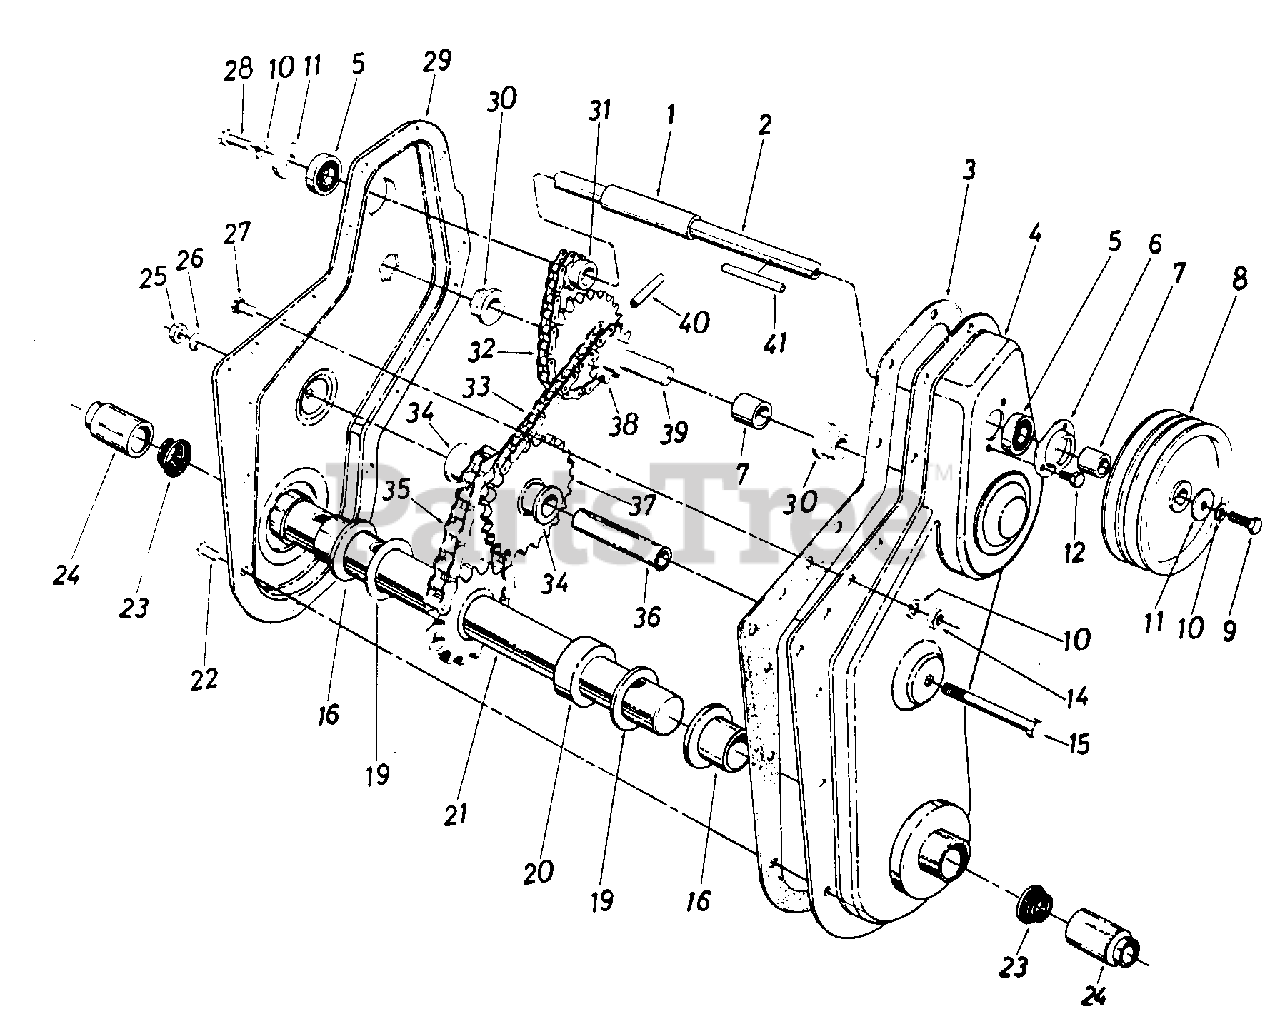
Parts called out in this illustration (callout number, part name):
2	SHAFT-JACK
3	GASKET
4	CHAIN CASE HALF-LH
5	BEARING-BALL
6	HOUSING-BRG
7	SPACER-.635 ID X .88 OD X 1.03
9	SCREW-HEX 5/16-18 X 10 SPEC
10	WASHER-LOCK-5/16
11	WASHER-FL-.312 X 1.125 X .125
12	SCREW-HEX WASH SF TAPP
14	NUT-HEX 5/16-18
15	SCREW-HEX 3/8-16 X 3.25
16	BEARING-KING PIN
19	WASHER-FL-1.03 ID X 1.62 X .03 HD
21	SHAFT-TINE
22	SCREW-HEX WASH SF TAPP
24	CAP-DUST
25	NUT-HEX 3/8-16
26	WASHER-LOCK-3/8
27	SCREW-HEX SEMS 5/16-18 X 1.00
28	SCREW-HEX 5/16-18 X .62
29	CHAIN CASE HALF-RH
30	BEARING-HEX FLANGE
31	SPROCKET ASSY-10T
32	#41 CHAIN 1/2 PITCH X 34 LINKS E
33	#420 CHAIN 1/2 PITCH X 48 LINKS
34	BEARING-FLANGE .626 ID
35	#50 CHAIN 5/8 PITCH X 28 LINKS
36	SHAFT-SPROCKET
37	SLEEVE ASSY-SPRKT
38	SLEEVE ASSY-SPRKT
39	SHAFT-SPROCKET
40	PIN-SPRING SPIRAL 1/4X1.5 HEAVY DT
41	KEY-SQ 3/16X1.50
